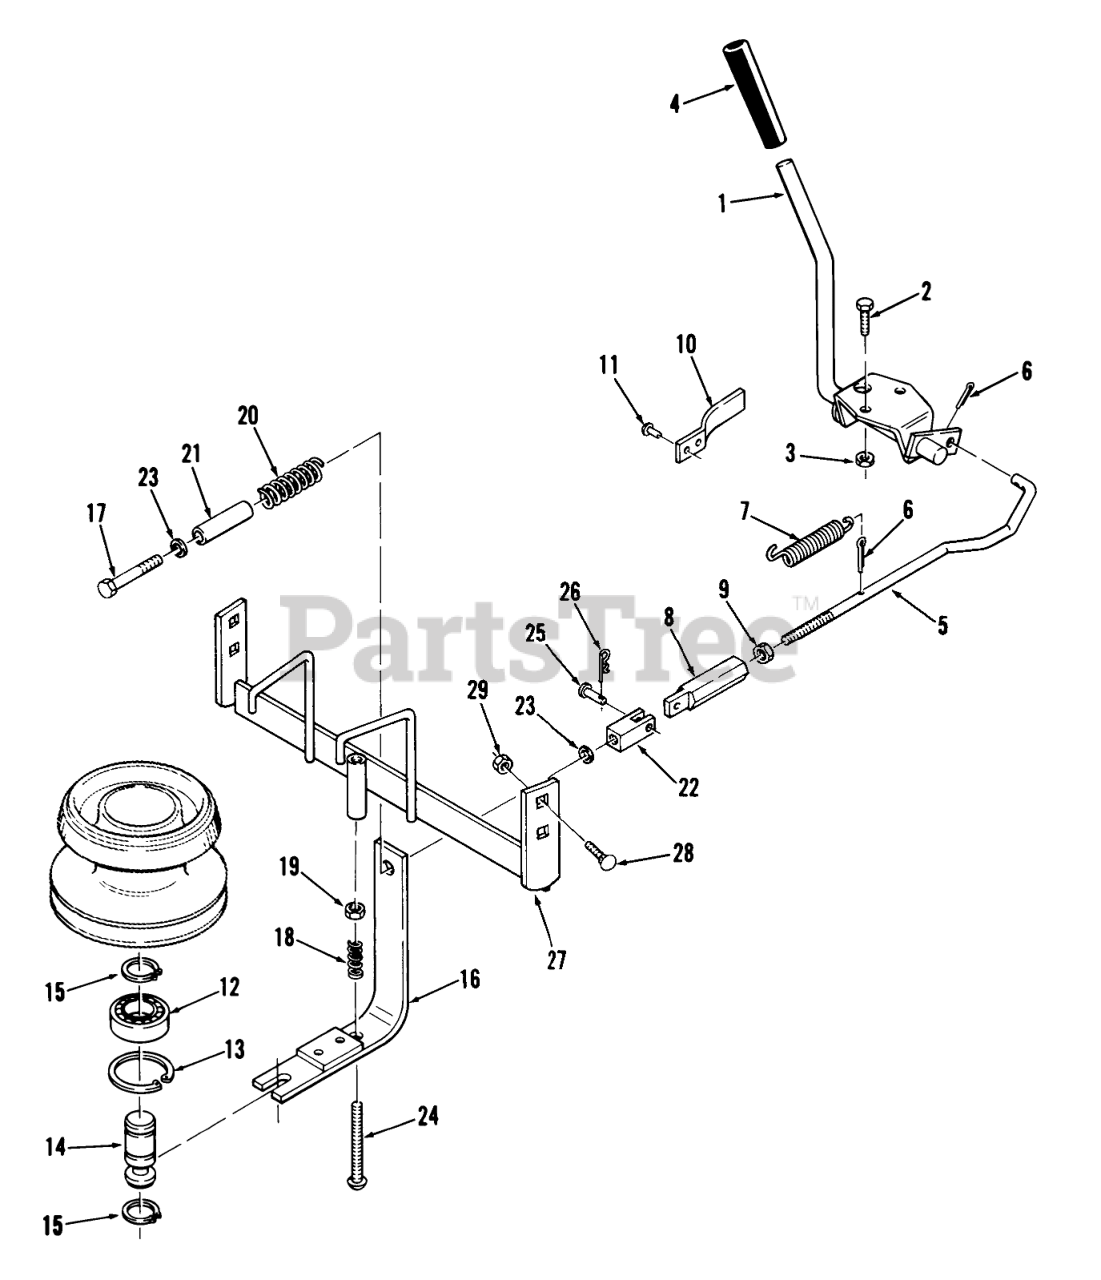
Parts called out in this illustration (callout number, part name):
1	PTO Clutch Lever
2	Bolt
3	Nut
4	GRIP
5	PTO Clutch Rod
6	Cotter Pin
7	Spring
8	Clutch Rod Adjust Block
9	Jam Nut 5/16-18
10	SPRING
11	RIVET
12	Bearing
13	Ring-Snap
14	SHAFT-CLUTCH HSG
15	RING-SNAP, EXTERNAL
16	Clutch Brake Bracket
17	HHCS
18	SPRING-COMPRESSION
19	Jam Nut 5/16-18
20	SPRING-CLUTCH
21	TUBE-CLUTCH SPACER
22	Block-Clutch Adjust
23	Collar
24	Pan HD Mach Screw 5/16-18 X 2
25	CLEVIS PIN
27	Clutch Mounting Bracket
28	Bolt
29	Nut
